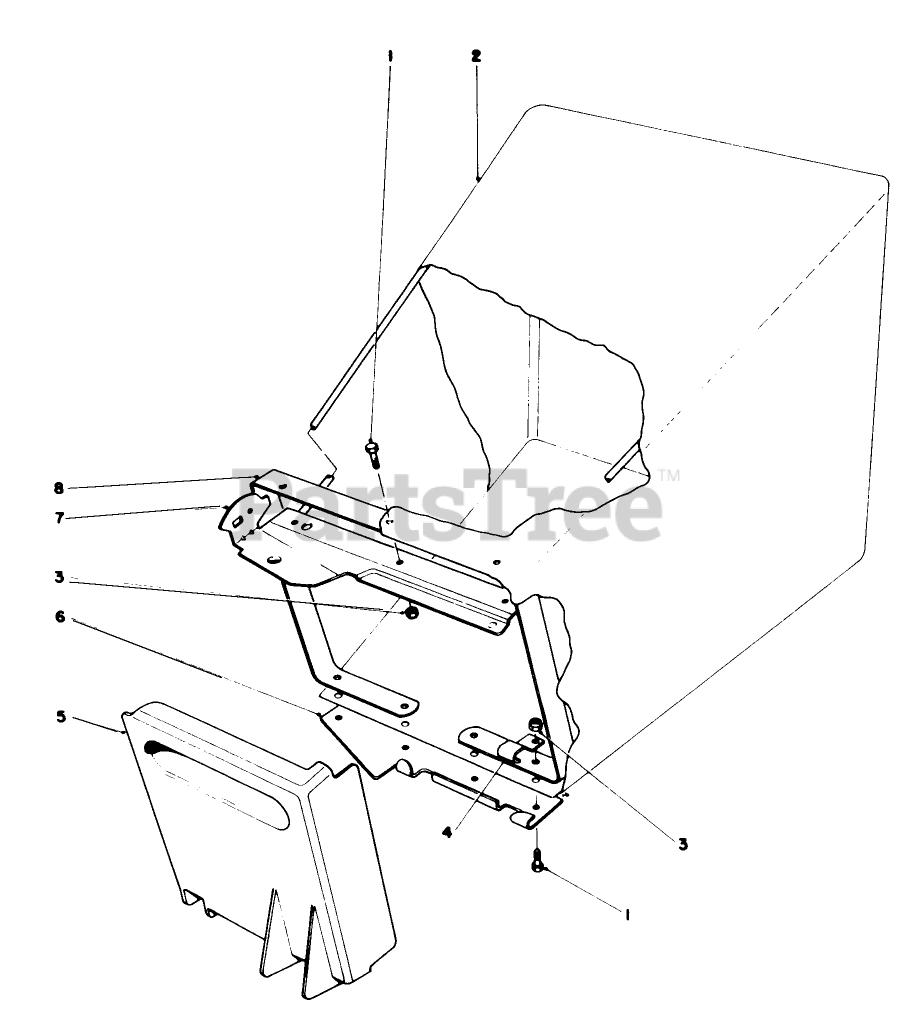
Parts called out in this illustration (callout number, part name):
1	SCREW-HWH
3	NUT-LOCK, SIDE
7	BAG FRAME ASM
8	LOWER BAG FRAME
